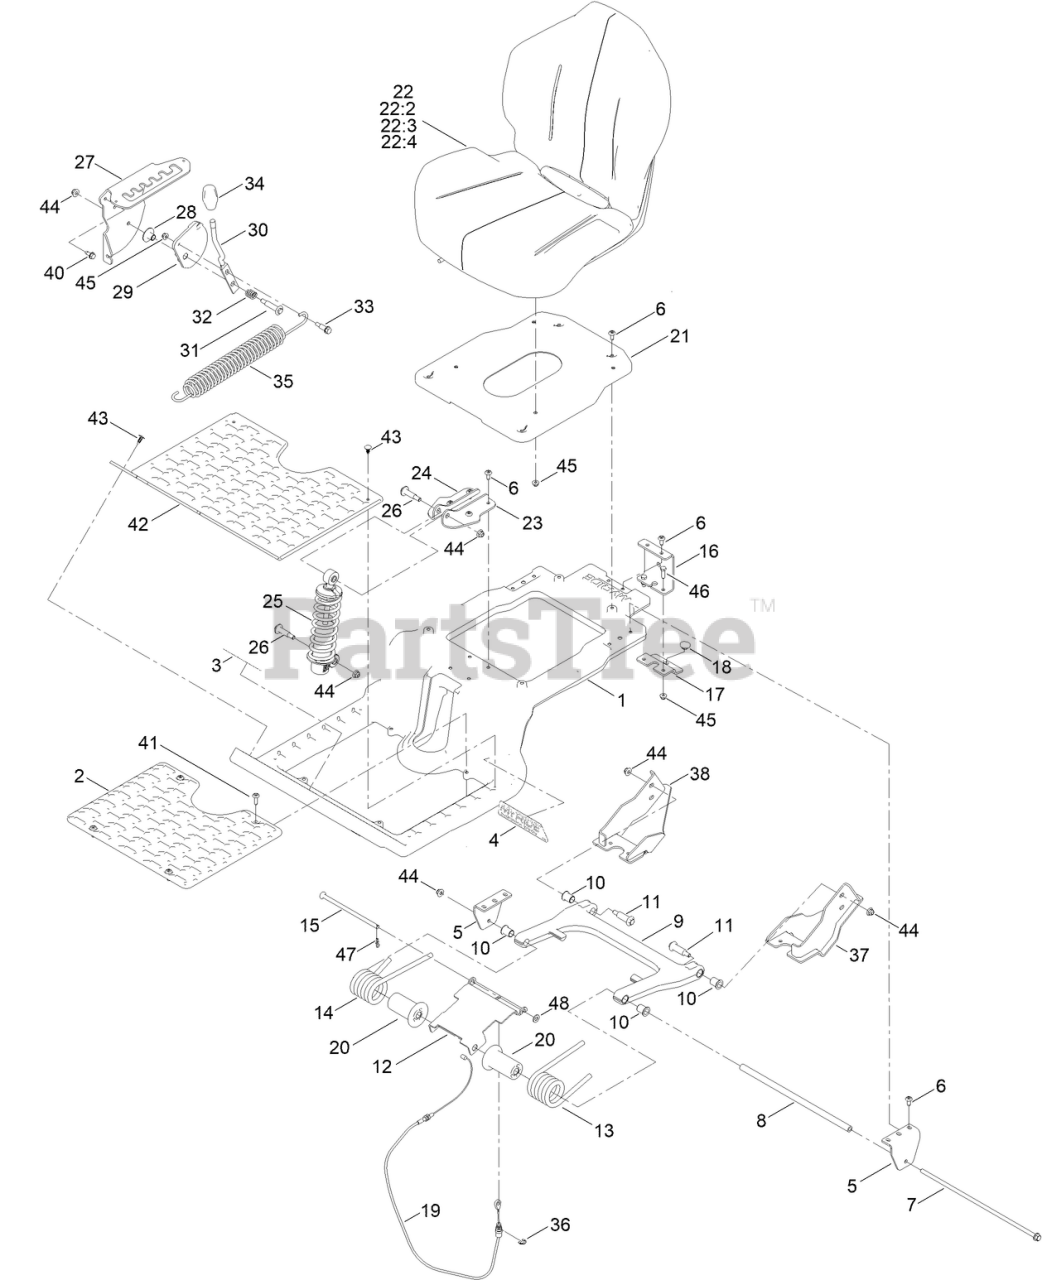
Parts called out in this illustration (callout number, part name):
1	PLATFORM, MYRIDE
2	PLATFORM, MYRIDE
3	DECAL - MYRIDE
4	DECAL - MYRIDE
5	BRACKET-MOUNT, SWING ARM
7	SCREW-HHF
8	TUBE-SPACER
9	ARM-SWING
10	BUSHING-FLANGE
11	BOLT-SHOULDER
12	PLATE-ADJUSTER
13	SPRING-TORSION, LH
14	SPRING-TORSION, RH
15	ROD-ADJUSTMENT
16	BRACKET-CABLE
17	BRACKET LOWER
18	BUMPER-SEAT
19	CABLE-ADJUSTMENT, MYRIDE
20	RETAINER-SPRING
21	PAN-SEAT [BLACK]
22	SEAT ASM - MILSCO CS180D
22:2	KIT-ADJUSTER
22:3	SWITCH-BAIL
22:4	COVER-SEAT
23	BRACKET-SHOCK MOUNT, UPPER (LH)
24	BRACKET-SHOCK MOUNT, UPPER (RH)
25	SHOCK/SPRING ASM
26	BOLT-SHOULDER
27	BRACKET-MR GATE
28	BUSHING - FLANGE
29	PULLEY-CAM
30	LEVER-ADJUSTMENT, THREADED
31	BOLT-SHOULDER
32	SPRING-COMPRESSION
33	BOLT-SHOULDER, HHF
34	KNOB-MR
35	SPRING-EXTENSION
36	RING-RETAINING, EXTERNAL
37	MOUNT-MR SWING ARM, LH
38	MOUNT-MR SWING ARM, RH
40	SCREW-HWHTF
41	SCREW-SPCL
42	FLOOR MAT
43	PLUG-PLASTIC
44	NUT-HF, NI
45	NUT-HF
46	SCREW-HH
47	PIN-HAIR
48	WASHER-FLAT
